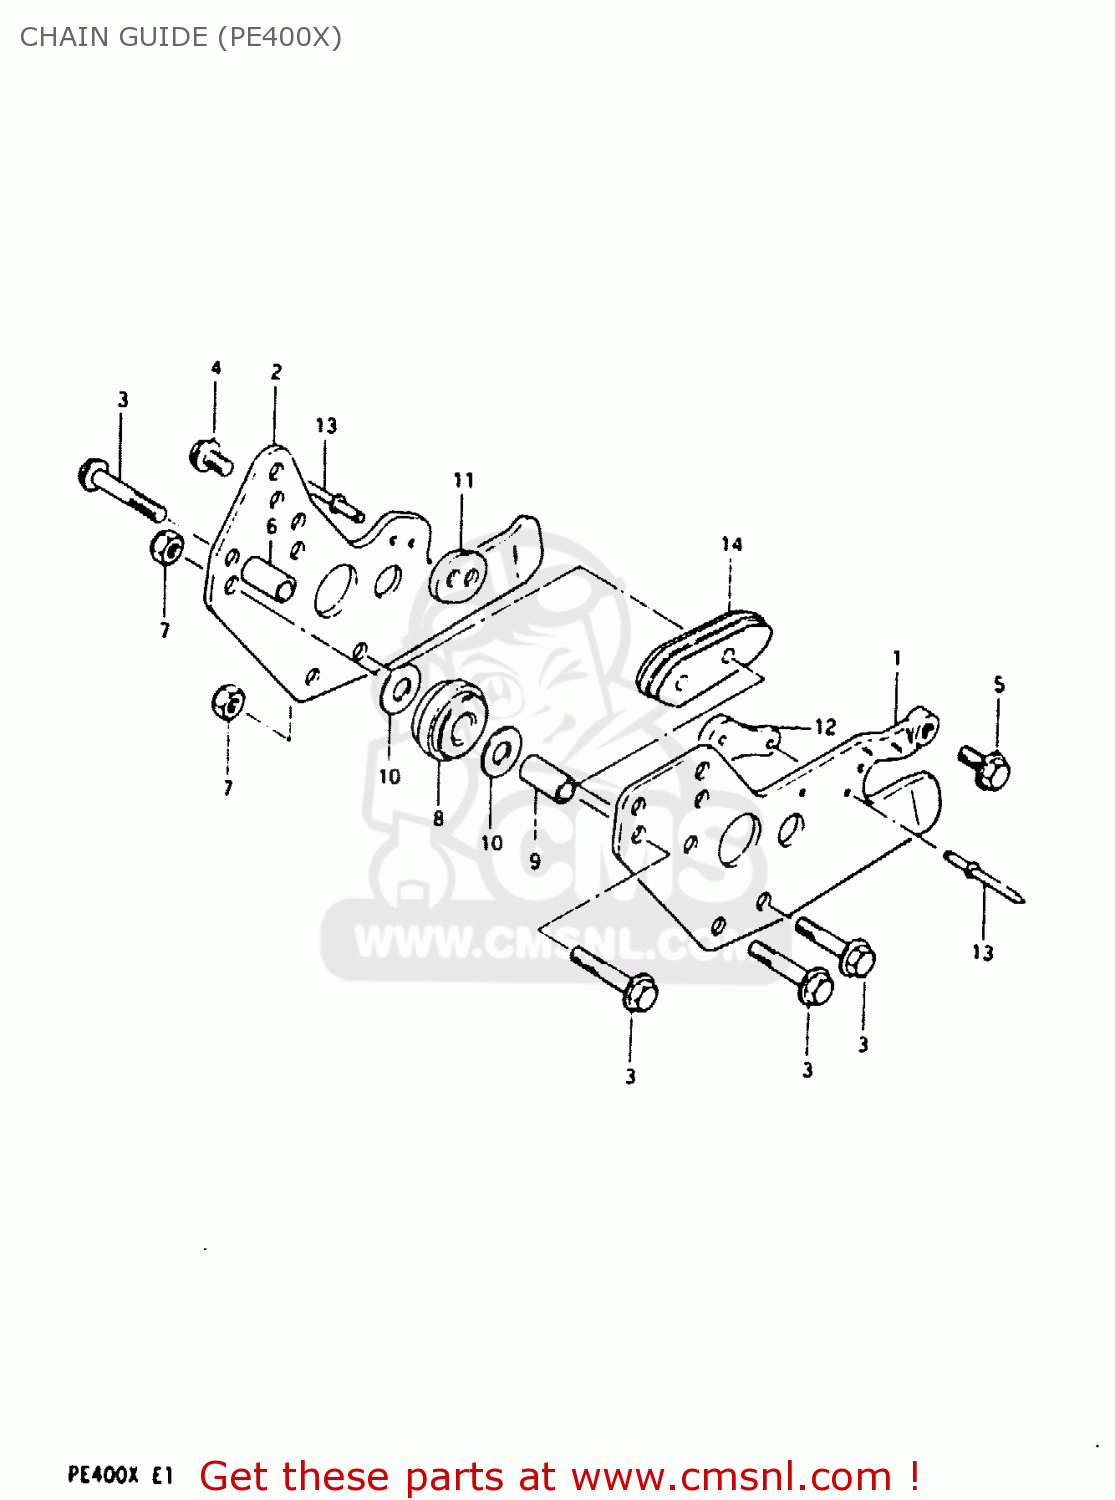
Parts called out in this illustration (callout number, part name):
1	PLATE,CHAIN GUIDE,OUTER
2	PLATE,GUIDE CHAIN
3	BOLT
4	BOLT
5	BOLT
6	SPACER(6.8X10X24.2)
7	NUT
8	ROLLER,CHAIN GUIDE
9	SPACER,CHAIN GUIDE ROLLER
10	WASHER
11	PAD,DRIVE CHAIN GUIDE
12	PAD,DRIVE CHAIN GUIDE
13	RIVET
14	DEFENSE,CHAIN GUIDE
